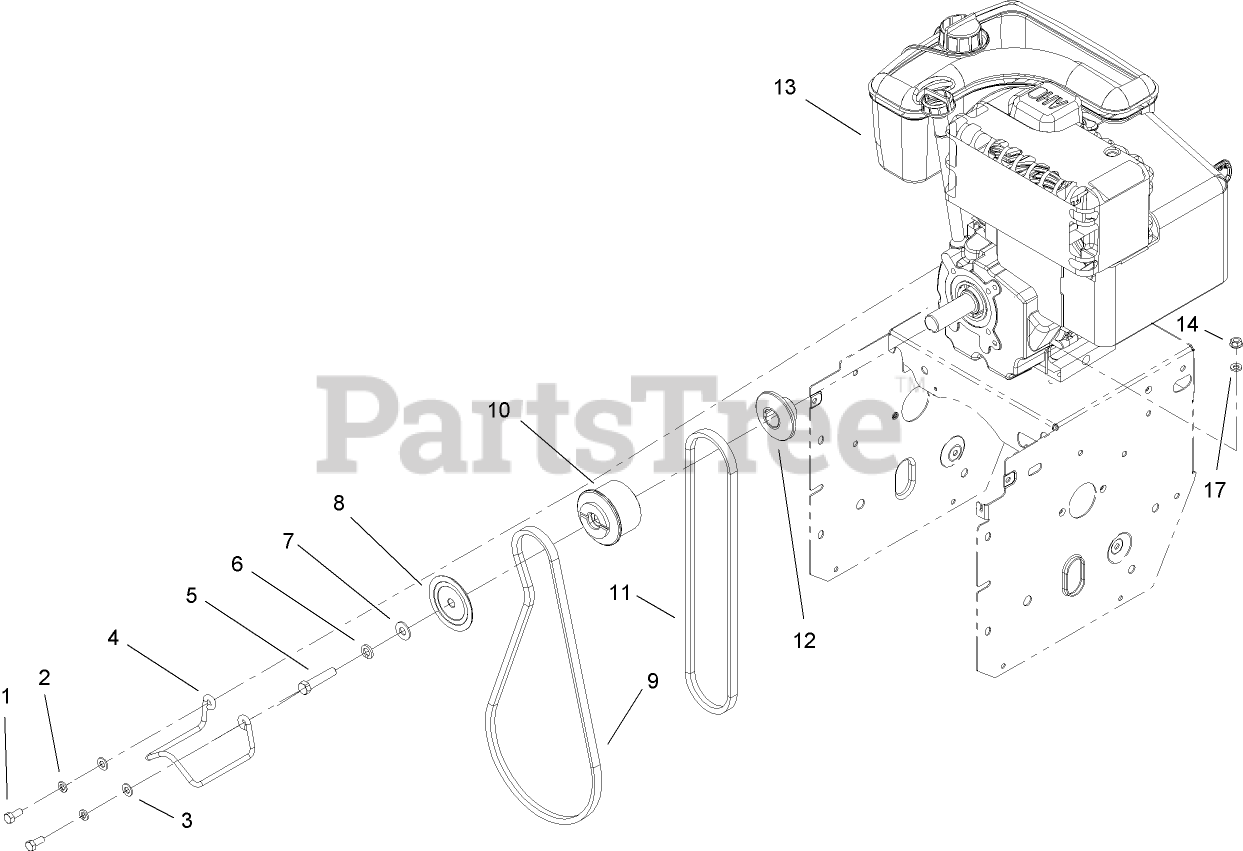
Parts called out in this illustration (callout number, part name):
1	SCREW-HH
2	WASHER-LOCK
3	WASHER-PLAIN
5	SCREW-HH
6	WASHER-LOCK
7	WASHER-FLAT
8	SHEAVE-HALF, IMPELLER
9	BELT-V
10	PULLEY-ENGINE, CENTER
11	V BELT-TRACTION
12	SHEAVE-HALF, TRACTION
13	Loose Parts Package
14	NUT-HF
17	WASHER-FLAT
